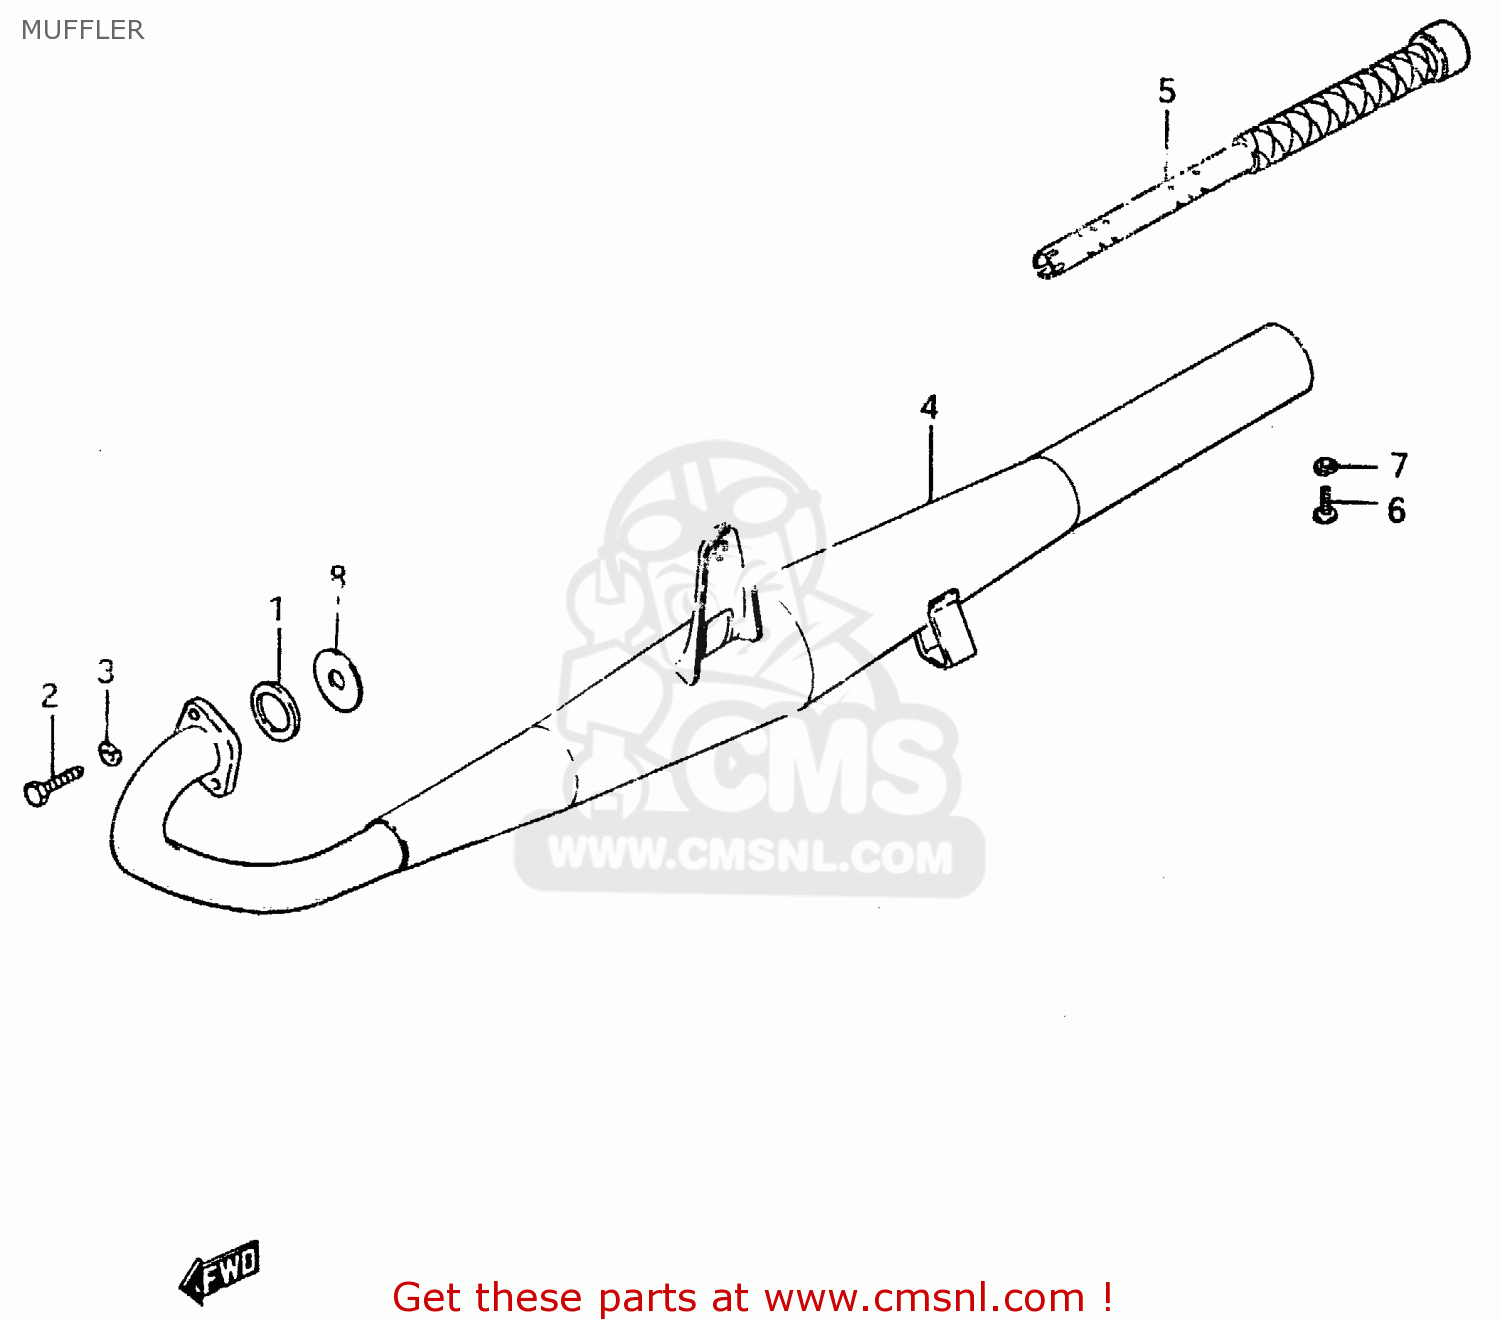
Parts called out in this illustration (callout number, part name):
1	GASKET,EXHAUST PIPE (NAS)
2	BOLT
3	LOCK WASHER
4	MUFFLER ASSY
5	PIPE, BAFFLE
6	BOLT(5X8)
7	LOCK WASHER
8	PLATE, EXHAUST PIPE
